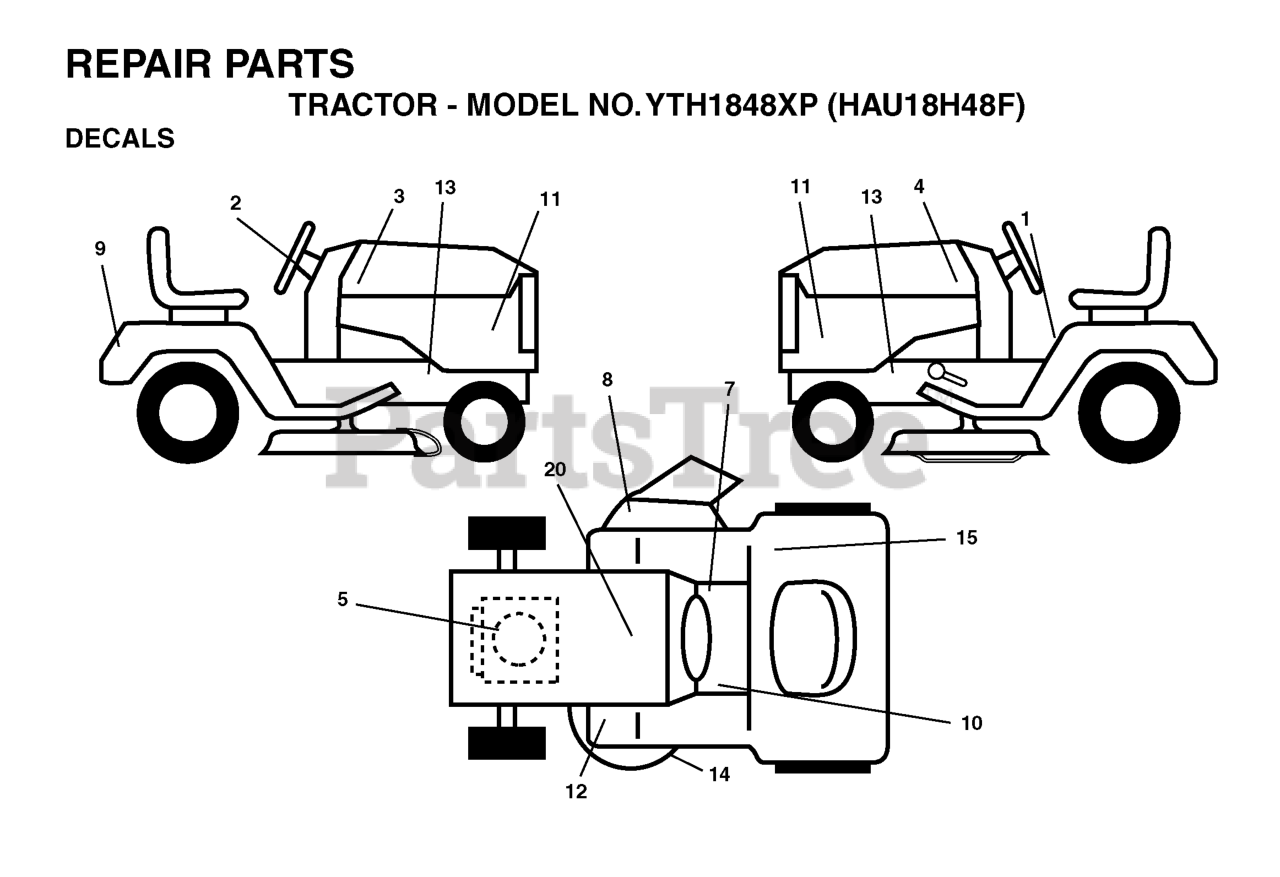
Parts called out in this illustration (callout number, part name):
1	DECAL READ OWNER'S MAN SYMS
2	DECAL.WHEEL.STEERING.HUSQ.PERM
3	HOOD DECAL
4	HOOD DECAL
5	DECAL ENGINE
7	DECAL PARK BRAKE
8	DECAL.INTERNATIONL.CUTFINGER
9	DECAL, FENDER
10	DECAL
11	DECAL HOOD
12	DECAL CLUTCH/BRAKE
14	DECAL V-BELT SCHEMATIC
15	DECAL
20	DECAL BTRY SYMBOLS
